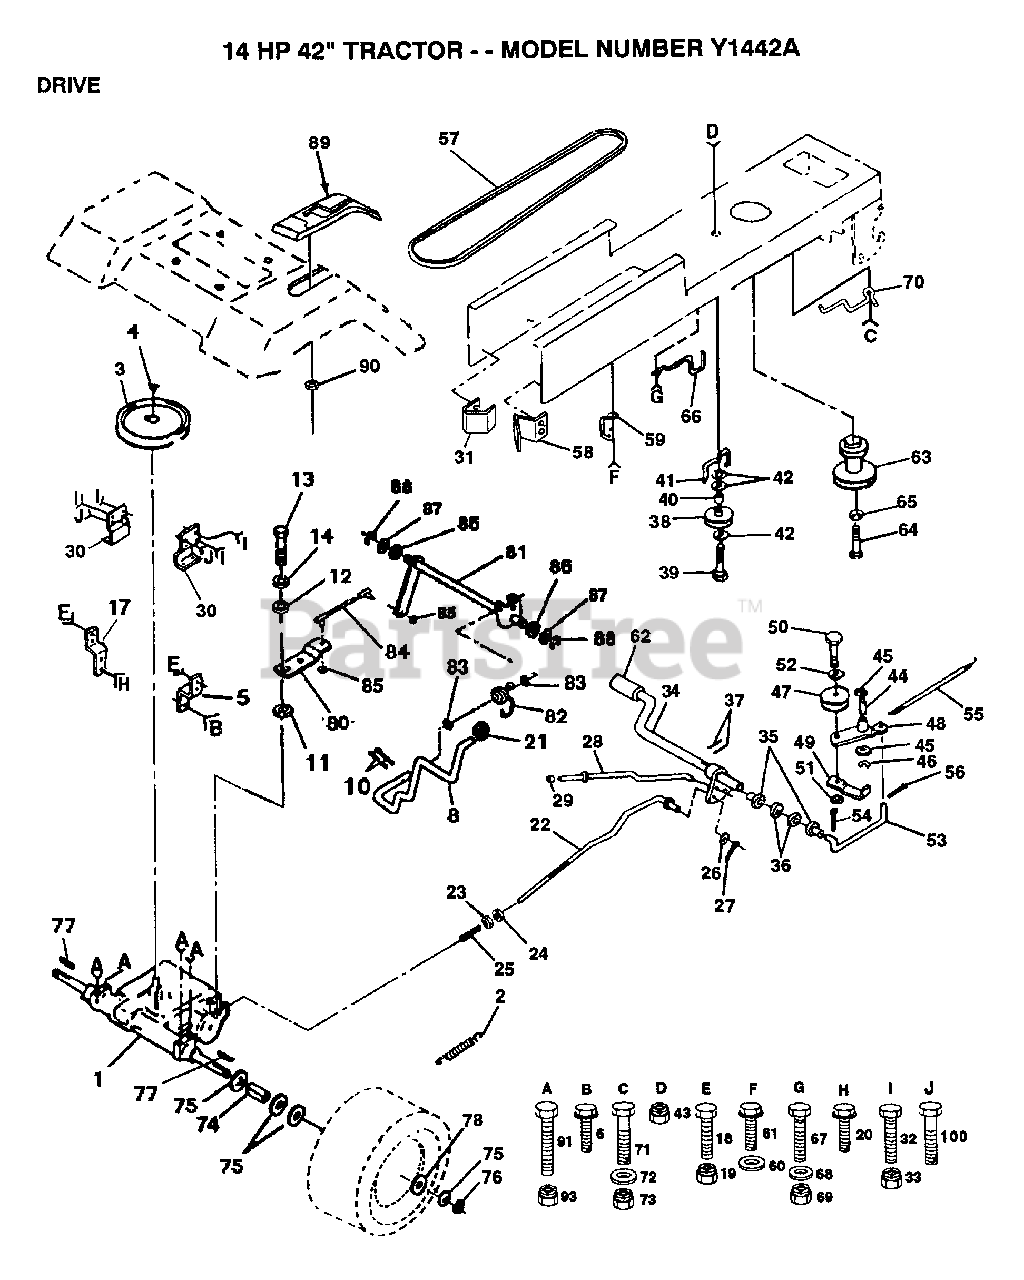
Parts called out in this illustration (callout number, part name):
3	PULLEY TRANS
5	STRAP TORQUE
6	SCREW
10	PIN COTTER 1/8
11	WASH-SHFT PLT LT
12	WASHER
14	LOCKWASHER
17	STRAP TORQUE
20	SCREW
21	KNOB T (1/2-HOLE)
22	BRAKE ROD
23	NUT
24	NUT
25	SPRING ROD LT
26	WASHER
27	COTTER PIN
28	PARKING BRAKE ROD
29	PLUNGER CAP T
30	TRANSAXLE MTG BKT
31	"KEEPER,BELT LH T"
32	BOLT
35	NYLON BEARING
36	WASHER LT
38	PULLEY.IDLER.FLAT
39	BOLT
40	SPACER T
41	BELT KEEPER LT
42	WASHER
44	"LY, BEARING"
45	WASHER LT
46	KLIP RING
48	ARM IDLER
49	RETAIN BELT
52	WASHER
53	"LINK, CLUTCH T"
54	COTTER PIN
55	"SPRING, RETURN LT"
56	COTTER PIN
58	"KEEPER,BELT RH T"
60	WASHER
61	SCREW
62	PEDAL COVER T
64	BOLT
65	LOCKWASHER
66	KEEPER.BELT.ENG.L
67	BOLT
68	WASHER
70	KEEPER BELT ENG
71	BOLT
72	WASHER
74	SPACER LT
75	WASHER
76	E-RING LT
77	SQUARE KEY
78	WASHER
80	SHIFT LEVER
81	SHAFT ASM CROSS
82	"SPRING,TORSION"
83	WASHER
84	TIE ROD
85	NUT 1/4-28
86	"BUSH,PIVOT T"
87	"WSHER,SHIM"
88	RING T
90	NUT
91	BOLT
100	SCREW
